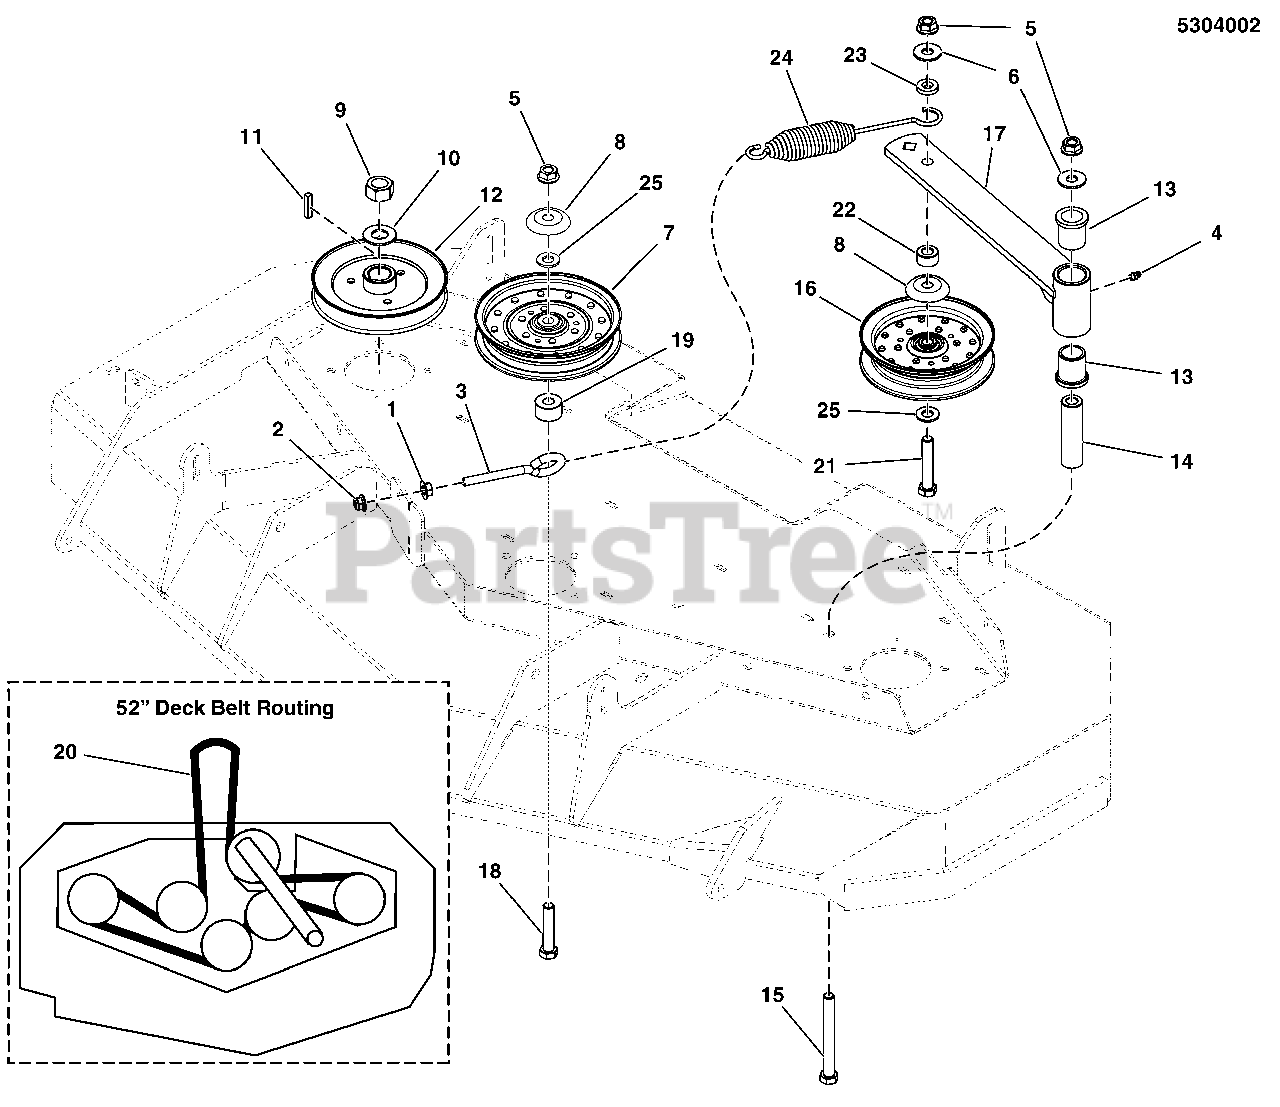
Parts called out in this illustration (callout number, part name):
1	NUT, Hex, Serrated Flange, 3/8-16 (S/N 616 & up)
2	NUT, Hex Flange, Nylock, 3/8-16
3	EYE BOLT, 3/8-16 X 6, 3.0 THRD, 1 EYE
4	GREASE FITTING, 1/4-28 STRAIGHT
5	NUT, Hex Flange, 1/2-13
6	WASHER, 1/2" USS
7	PULLEY, FLAT IDLER, 6-3/4"
8	SHIELD, PULLEY BEARING, CZ
9	NUT, 3/4-16 Hex (Included with Complete Spindle Assembly)
10	WASHER, Belleville, 3/4
11	KEY, 1/4 SQ. X 1-1/4
12	PULLEY, 5.926OB X .985ID, SINGLE B-SEC
13	BUSHING, FLANGE
14	SPACER, .52 X 1.00 X 3.50
15	BOLT, 1/2-13 X 4-1/2 GD5 YZ
16	PULLEY, DEEP V-IDLER, 6.25"OD X 1/2"ID
17	WELD, IDLER ARM - 52" - BLK
18	BOLT, 1/2-13 X 2-1/2 GD5 YZ
19	SPACER, .52 X 1.25 X .70, PM, CZ
20	BELT, 5V SEC, 162.4" EL, DECK DRIVE, ARAMID, WRPD, RC
21	BOLT, 1/2-13 X 2-3/4 GD5 YZ
22	SPACER, .52 X 1.00 X .56
23	SPACER, .52 X 1.00 X .22, PM, CZ
24	SPRING-EXT, 1.25OD X 9.3LG X .142WR, BLK
25	WASHER, 1/2
